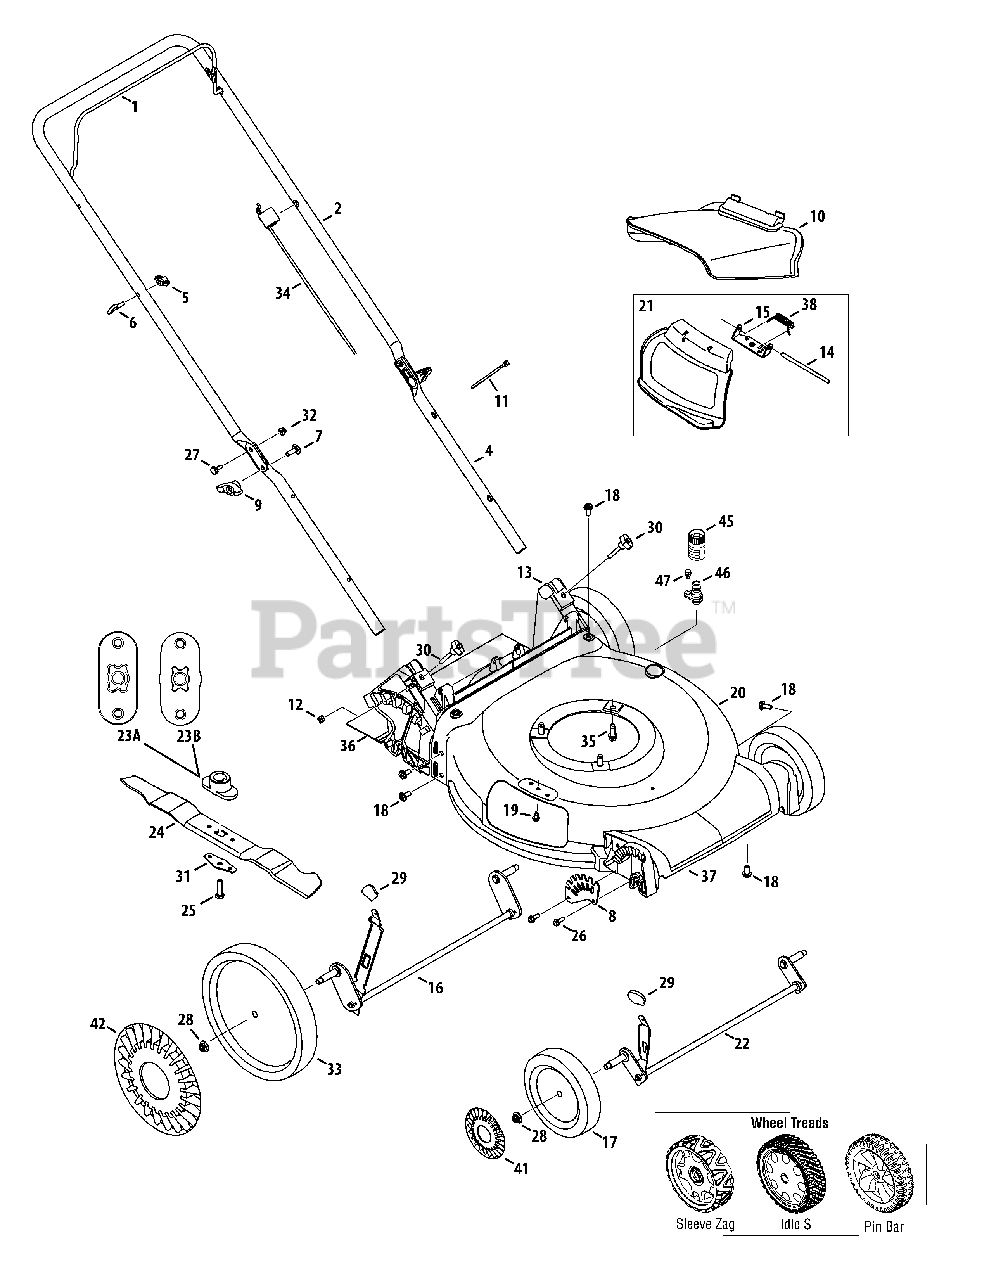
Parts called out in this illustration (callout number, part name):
1	Blade Control Handle - Black
2	Upper Handle - Black (adjustable)
4	Lower Handle
5	Knob 1/4-20
6	Rope Guide Bolt
7	Carriage Bolt 5/16-18
8	Front Height Adjustment Plate
9	Wing Knob 5/16-18 Black
10	Chute Deflector
11	Cable Tie
12	Sq. Nut 1/4-20
13	Rear Baffle
14	Hinge Pin
15	Chute Deflector Bracket
16	Rear Axle Ass'y - 11" wheel
17	Wheel Ass'y 7 x 2.0 Sleeve Zag Black
18	Hex Hd. Cap Screw 5/16-14 x .75
19	Sems TT Screw 1/4-20 x .50
20	21" Deck Ass’y
21	Hinged Mulch Plug Ass'y (Incl. ref. no.15, 38 & 14)
22	Front Axle Ass'y - 7 " wheel
23A	Blade Adapter
24	21" Mulching Blade
25	Hex Bolt 3/8-24 x 1.5" Lg. (Gr 8)
26	Screw, 1/4-15 x .750
27	Shoulder Screw .375 x .126 x 1/4-20
28	Flange Locknut 3/8-16 Gr. F Nylon
29	Knob (Black)
30	Knob 1/4-20 x 1.725 Black
31	Blade Bell Support
32	Flanged Lock Nut 1/4-20 Gr. F Nylon
33	Wheel Ass'y 11 x 2 Sleeve Zag Black
34	Control Cable, 158 cc B&S
35	Hex Wash HD Tap Scr 3/8-16 x .88
36	Trailing Shield 4.54 x 17.37
37	Front Axle Cover
38	Torsion Spring
41	Hub Cap (11")
42	Hub Cap (7")
45	Water Nozzle Adapter
46	Deck Water Nozzle
47	Shoulder Screw 1/4-20 x .50
